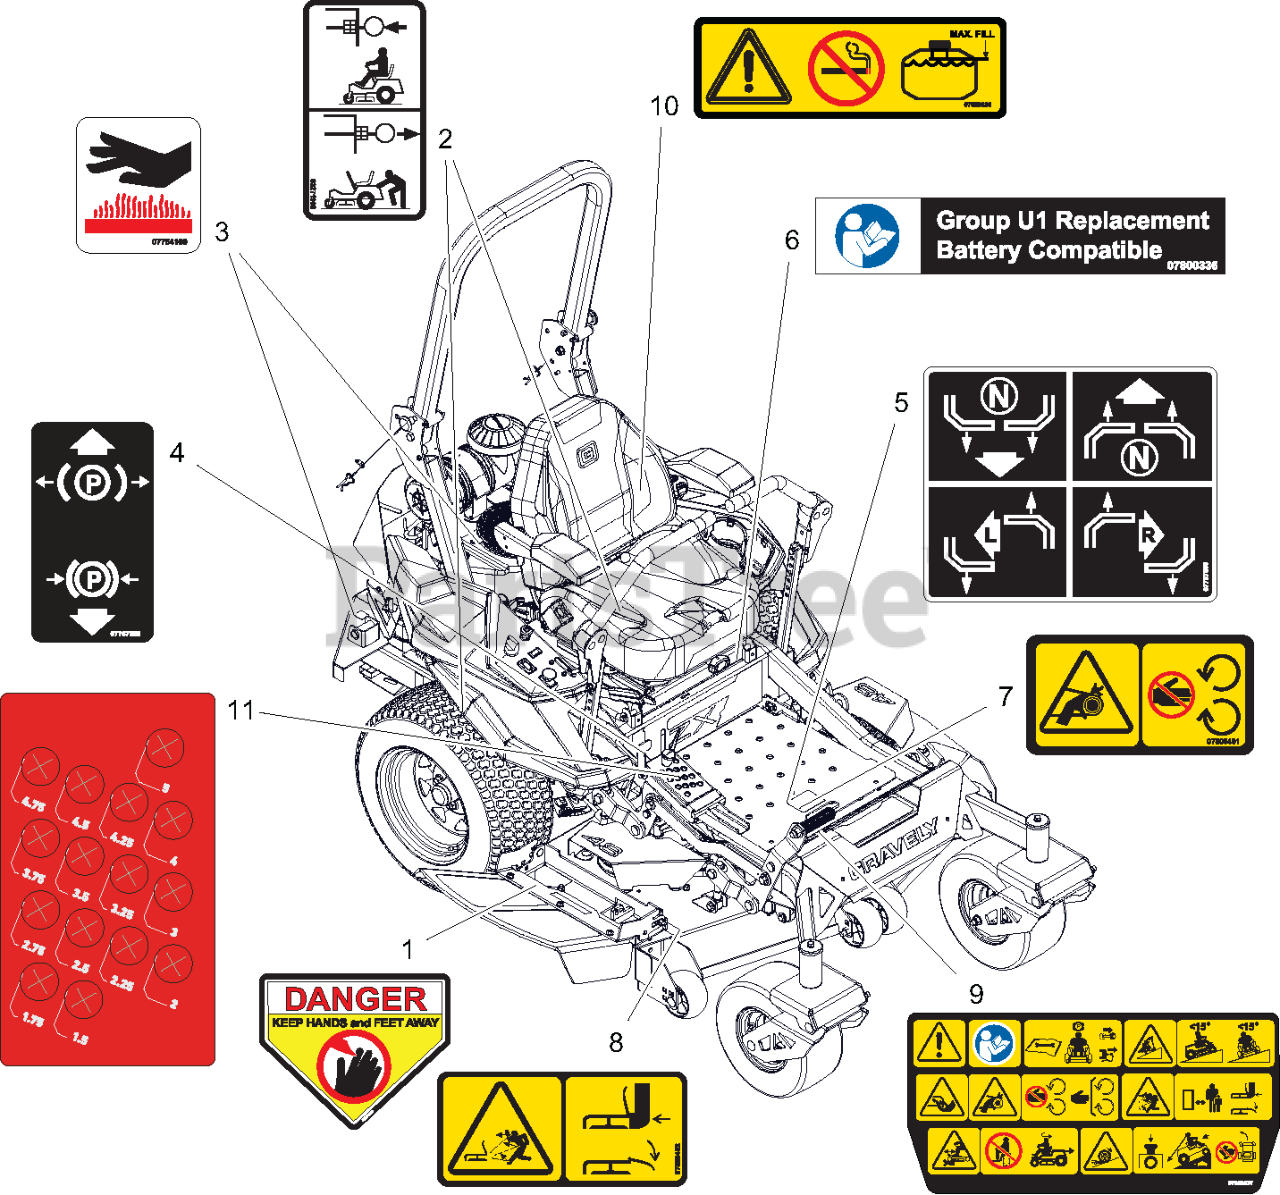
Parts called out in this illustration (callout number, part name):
1	DECAL, DANGER
2	DECAL, TRANSMISSION DISCONNECT
3	DECAL, HOT SURFACE
4	DECAL, PARKING BRAKE LEVER
5	DECAL, INSTRUCTIONAL-STEERING
6	DECAL, U1 BATTERY REPLACEMENT
7	DECAL, SAFETY - GUARDING
8	DECAL, SAFETY - DECK GUARDING
9	DECAL, MAIN SAFETY
10	DECAL, FUEL WARNING
11	DECAL, HEIGHT OF CUT
